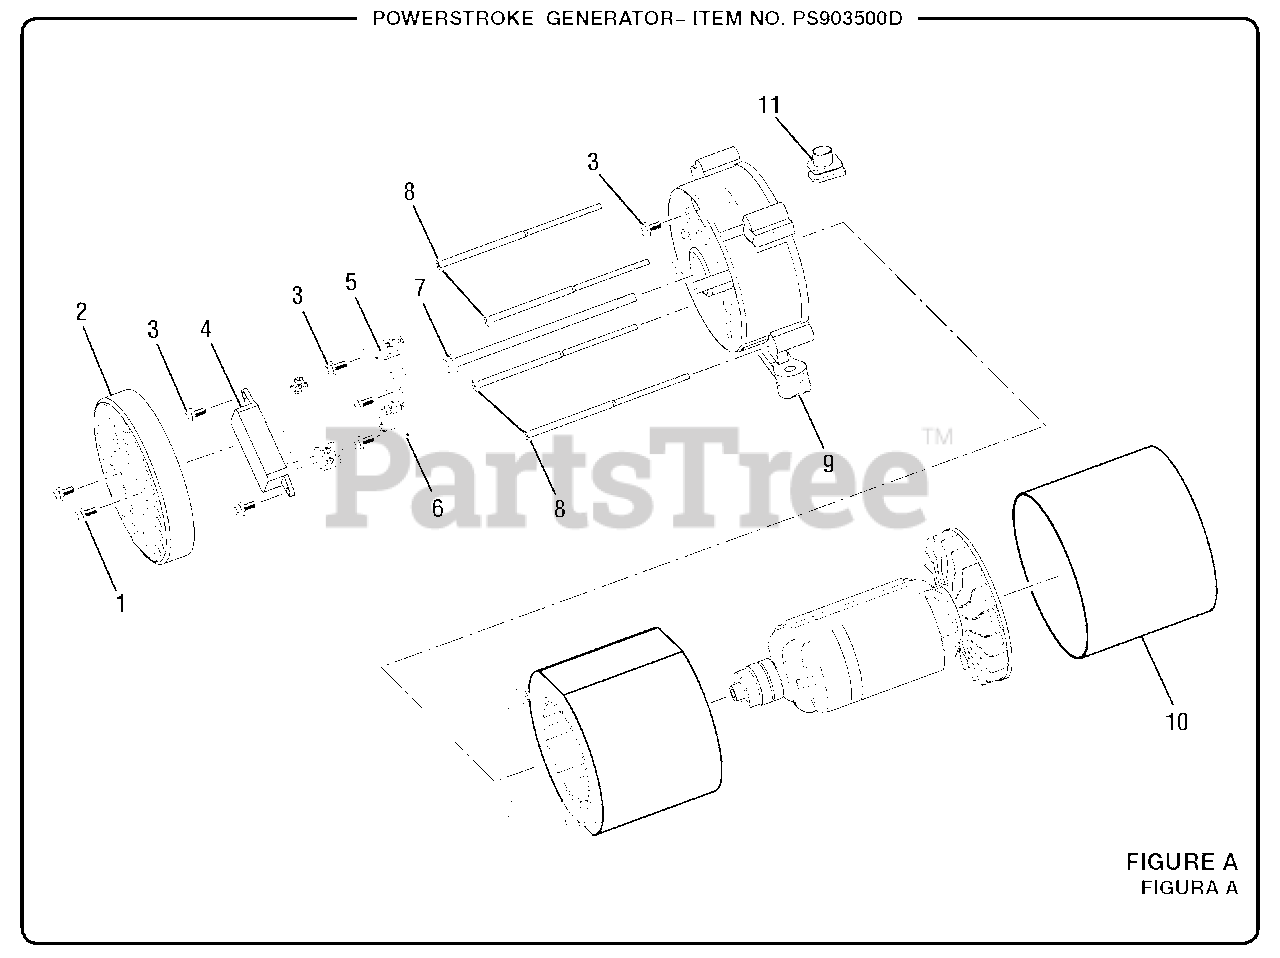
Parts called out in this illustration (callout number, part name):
1	Bolt (M5 x 16 mm, Hex Hd.)
2	Brush Cover
3	Bolt (M5 x 10 mm)
4	Automatic Voltage Regulator
5	Brush Assembly
6	Terminal Block
7	Rotor Bolt
8	Stator Bolt
9	Bearing Housing
10	Generator Head Cover
11	Rubber Boot
